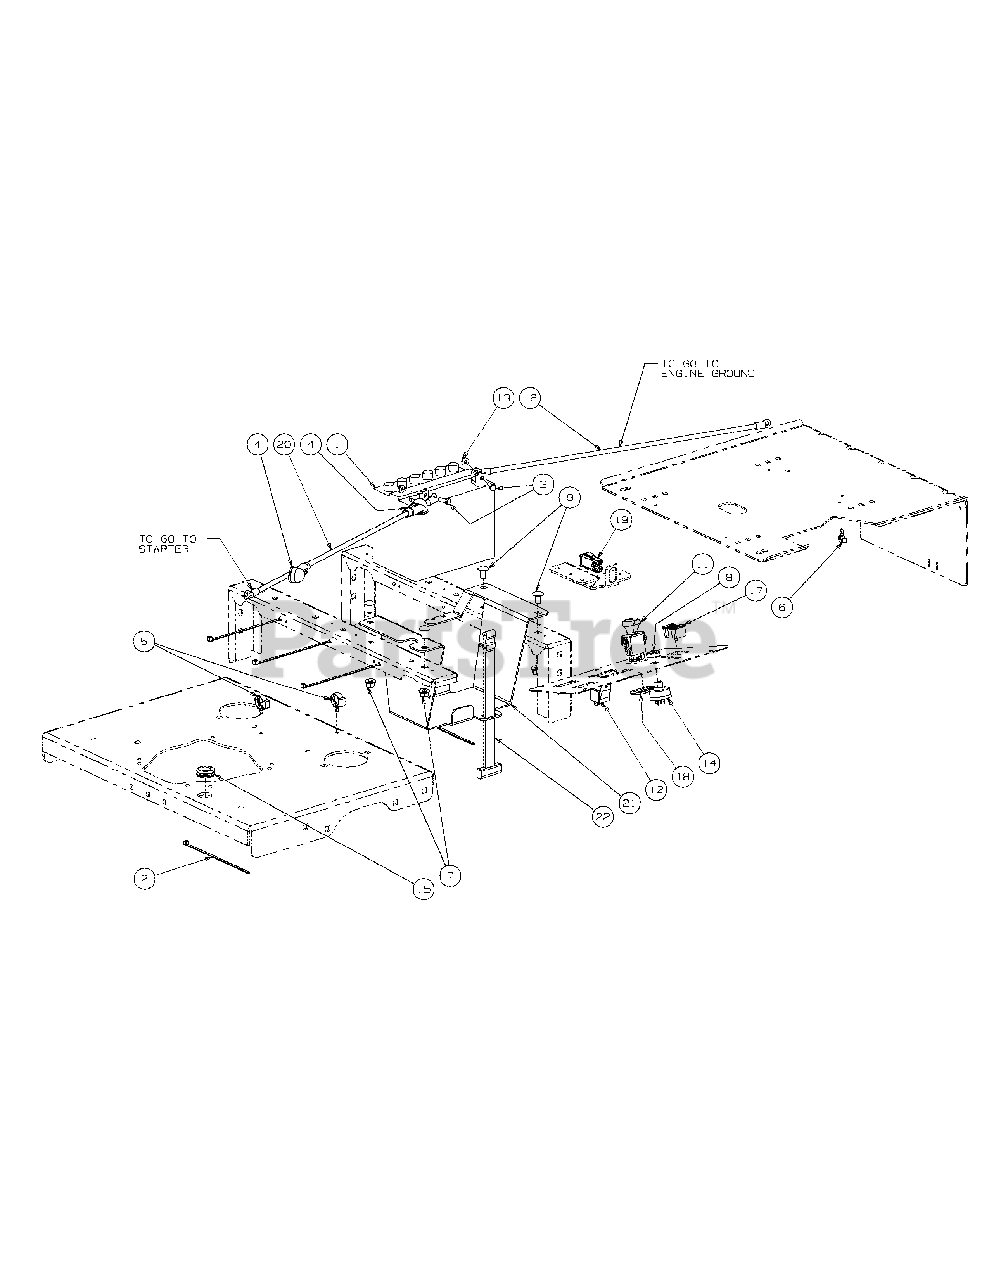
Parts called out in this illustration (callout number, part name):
1	Battery, 12V 225CCA 30 Min
2	Tie, Cable, 3/16 x .05 x 7.4"
3	Screw, Hex, Cap, 1/4-20 x .75
4	Boot, 1" OD Rubber Battery-PST, Red
5	Electrical Conduit Clip, 5/8
6	Electrical Conduit Clip, 3/8
7	Flange Lock, Hex Nut, 3/8-16
8	Nut, W/Cap, 5/8-32 Ignition
9	Carriage Bolt, 3/8-16 x .75 Long
11	Switch, Electric, PTO
12	Relay, 12V 40A
13	Lock Nut, 1/4-20
14	Switch, Ignition, 6 Pin includes:
15	Grommet, .75 ID
16	Cable, Battery Red, 34"
17	Meter, Hour includes:
18	Bracket, PTO Switch Retainer
19	Switch, Safety N.O./N.C.
20	Cable, Battery, Red, 42"
21	Battery Bracket
22	Strap, Battery
23	Harness Assembly
